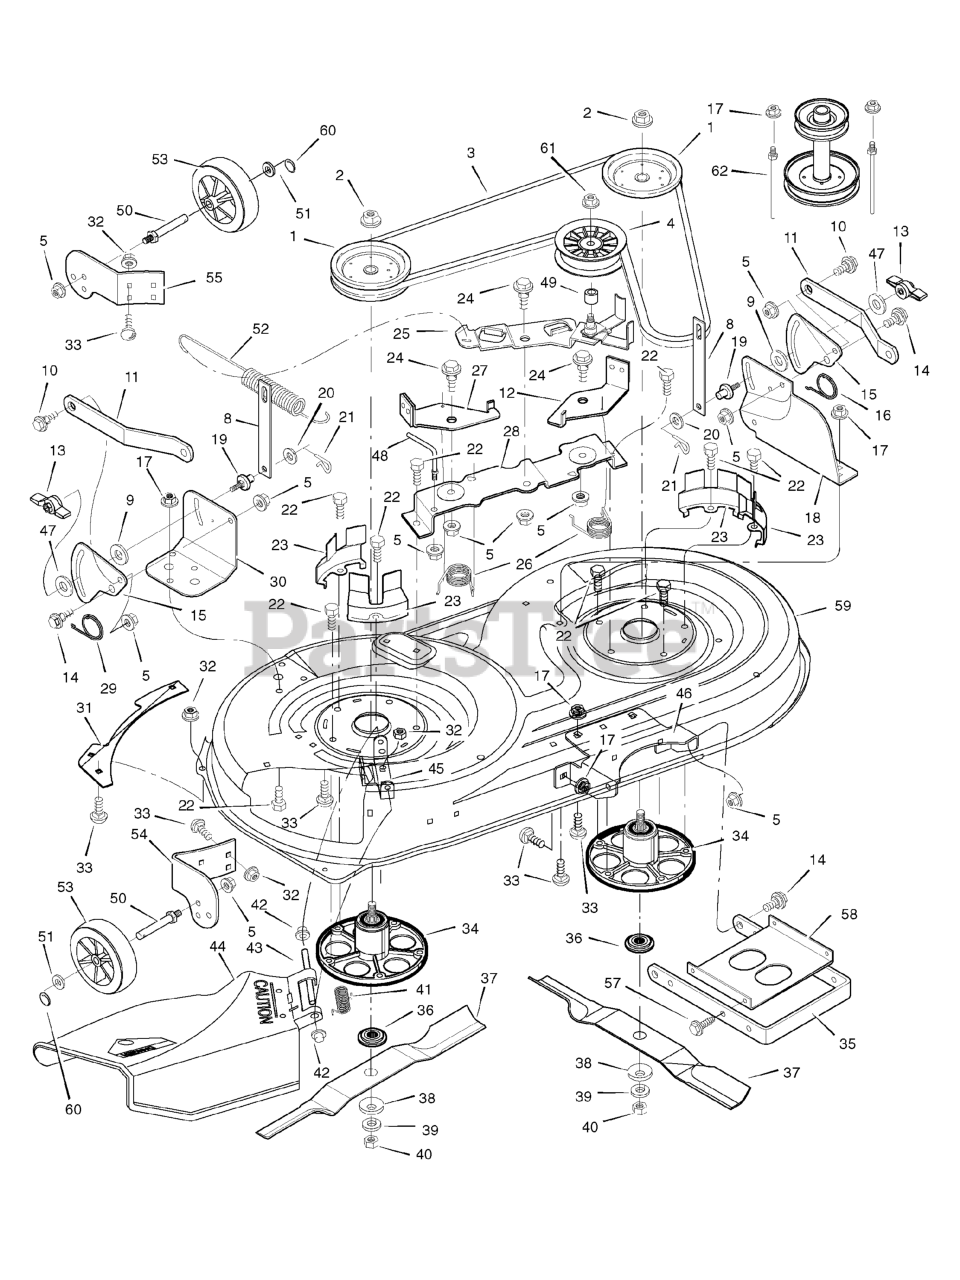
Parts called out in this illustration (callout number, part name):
1	PULLEY, Jackshaft
2	NUT, Hex
3	BELT, Mower Drive
4	PULLEY, Idler
5	NUT, Flange
8	LINK, Lift
9	PAD, Friction
10	BOLT, Shoulder
11	BRACKET, Suspension
12	PAD ASSEMBLY, Left Brake
13	KNOB
14	BOLT, Shoulder
15	PLATE, Suspension
17	NUT, Flange
18	BRACKET, Suspension
19	PIN, Hanger
21	PIN, Hair
22	BOLT
23	COVER, Pulley
24	BOLT, Shoulder
25	ARM, Idler
27	PAD ASSEMBLY, Right Brake
28	BRACKET, Brake
30	BRACKET, Suspension
32	NUT, Flange
33	BOLT, Carriage
34	MANDRELL HOUSING
35	BRACKET, Suspension
36	ADAPTER, Blade
42	CAP, Push On
43	ROD, Deflector
44	DEFLECTOR ASSEMBLY
45	BRACKET, Deflector Hinge
46	BRACKET, Front Hanger
48	GIUDE, Belt
50	BOLT, Gauge Wheel
52	SPRING, Extension
53	WHEEL, Gauge
54	BRACKET, Right Wheel
55	BRACKET, Left Wheel
59	Housing, Blade, Complete (NO LONGER AVAILABLE)
59	Housing, Blade (Housing Only)
60	RING, Locking
61	NUT, Flange
62	GUIDE, Belt
